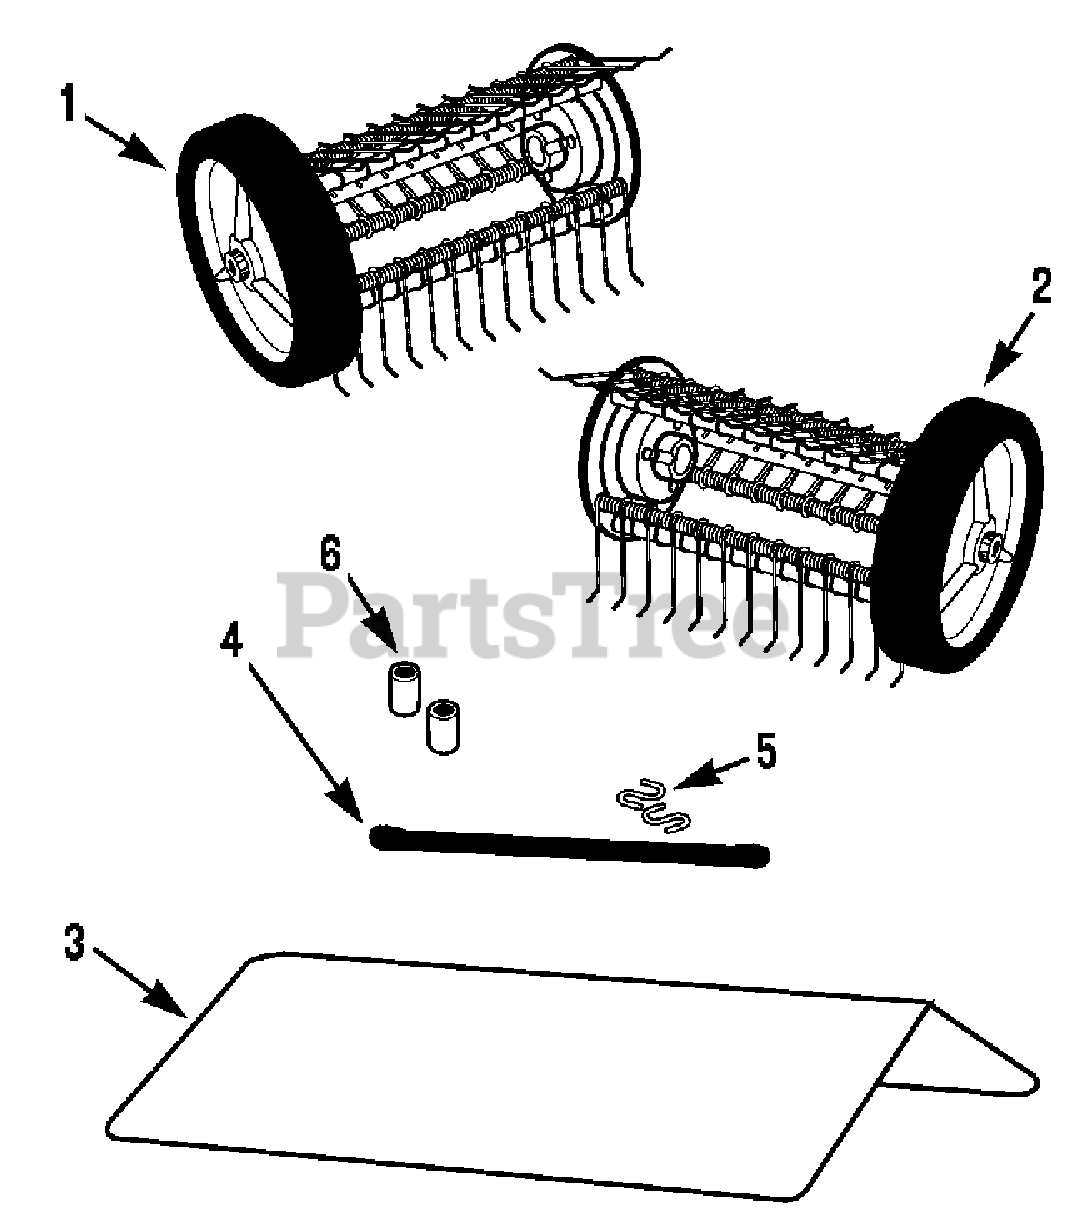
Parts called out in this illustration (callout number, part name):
1	Rake Assembly - left side
2	Rake Assembly - right side
3	Debris Shield. Ind. two decals
4	Mounting Strap
6	1-1/4" long Spacer
